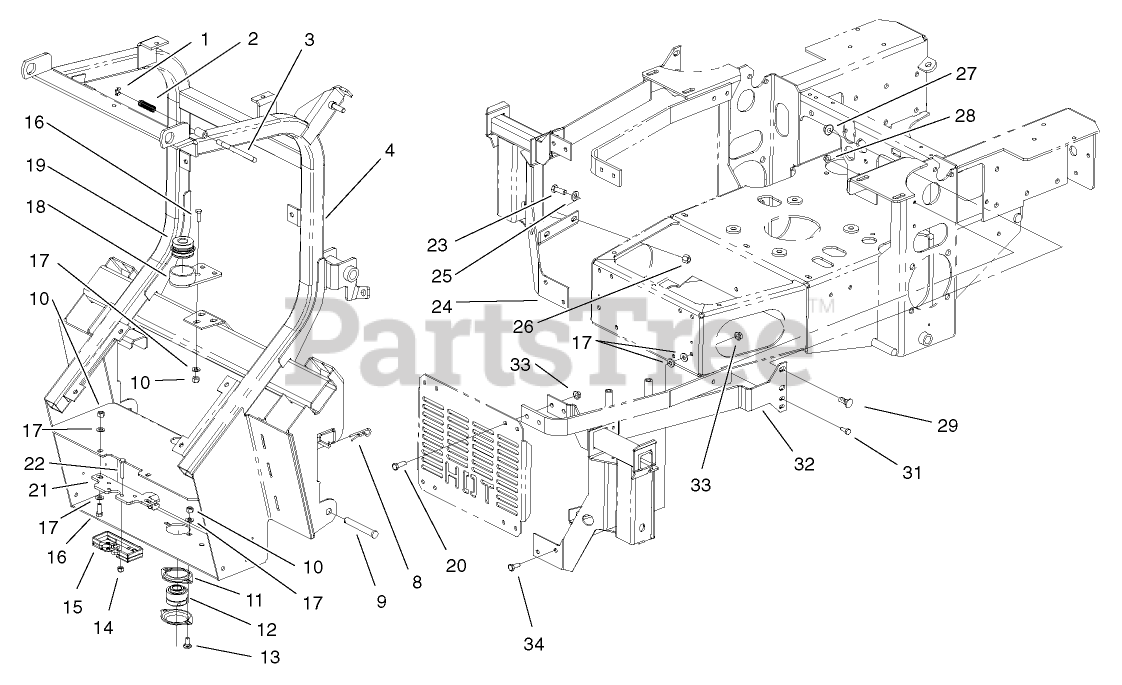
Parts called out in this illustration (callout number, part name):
2	SPRING
4	FRAME ASM
8	PIN-COTTER
9	PIN-CLEVIS
10	NUT-LOCK, NI
11	FLANGE-BEARING
12	BEARING-SPHERICAL
13	BOLT-CARR
14	NUT-LOCK, NI
15	LATCH-ROTOR
16	SCREW-HH
17	WASHER-PLAIN
18	Bearing Flange ASM
19	BEARING-CYLINDRICAL
20	SCREW-HH
21	BRACKET-LATCH
22	SCREW-HH
23	SCREW-HH
24	LH BAGGER MOUNT ASM
25	WASHER-FLAT
26	NUT-LOCK, NI
27	NUT-HF
28	NUT-HF
29	SCREW-CARR
31	SCREW-HH
32	RH BAGGER MOUNT ASM
33	NUT-HF
34	SCREW-HH
